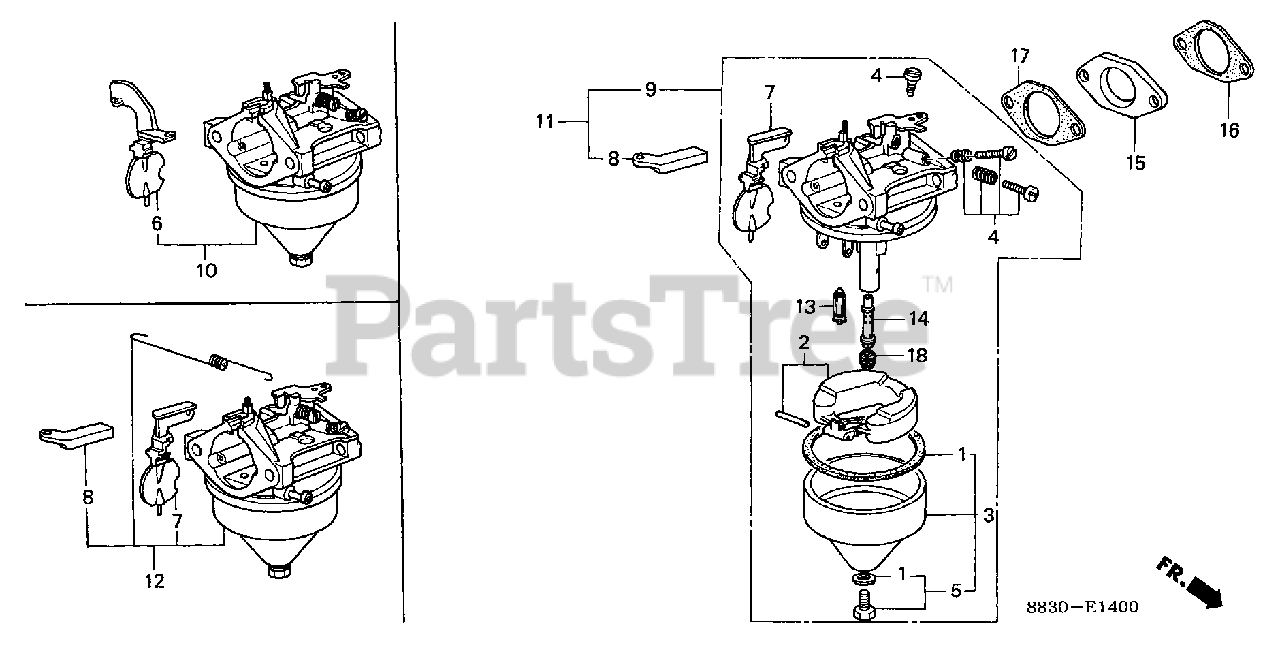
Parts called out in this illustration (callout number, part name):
1	GASKET SET
2	FLOAT SET (CARBURETOR NO.)
3	CHAMBER SET, FLOAT
4	SCREW SET A (CARBURETOR NO.)
5	SCREW SET
6	CHOKE SET (CARBURETOR NO.)
7	CHOKE SET (CARBURETOR NO.)
8	ARM, CHOKE LEVER (CARBURETOR NO.)
9	CARBURETOR ASSY. (BB30A G)
9	CARBURETOR ASSY. (BB30A D)
10	CARBURETOR ASSY. (BB30A G)
10	CARBURETOR ASSY. (BB30A A)
10	CARBURETOR ASSY. (BB30A D)
11	CARBURETOR ASSY. (BB30A G)
11	CARBURETOR ASSY. (BB30A B)
11	CARBURETOR ASSY. (BB30A D)
12	CARBURETOR ASSY. (BB30A G)
12	CARBURETOR ASSY. (BB30A D)
13	VALVE, FLOAT (CARBURETOR NO.)
14	NOZZLE, MAIN (CARBURETOR NO.)
15	INSULATOR, CARBURETOR
16	GASKET, INSULATOR
17	GASKET, CARBURETOR
18	JET, MAIN (#65) Use up to Engine SN BB30A D.
18	JET, MAIN (#68) Use up to Engine SN BB30A D.
18	JET, MAIN (#70) Use up to Engine SN BB30A D.
18	JET, MAIN (#72) (CARBURETOR NO.)
